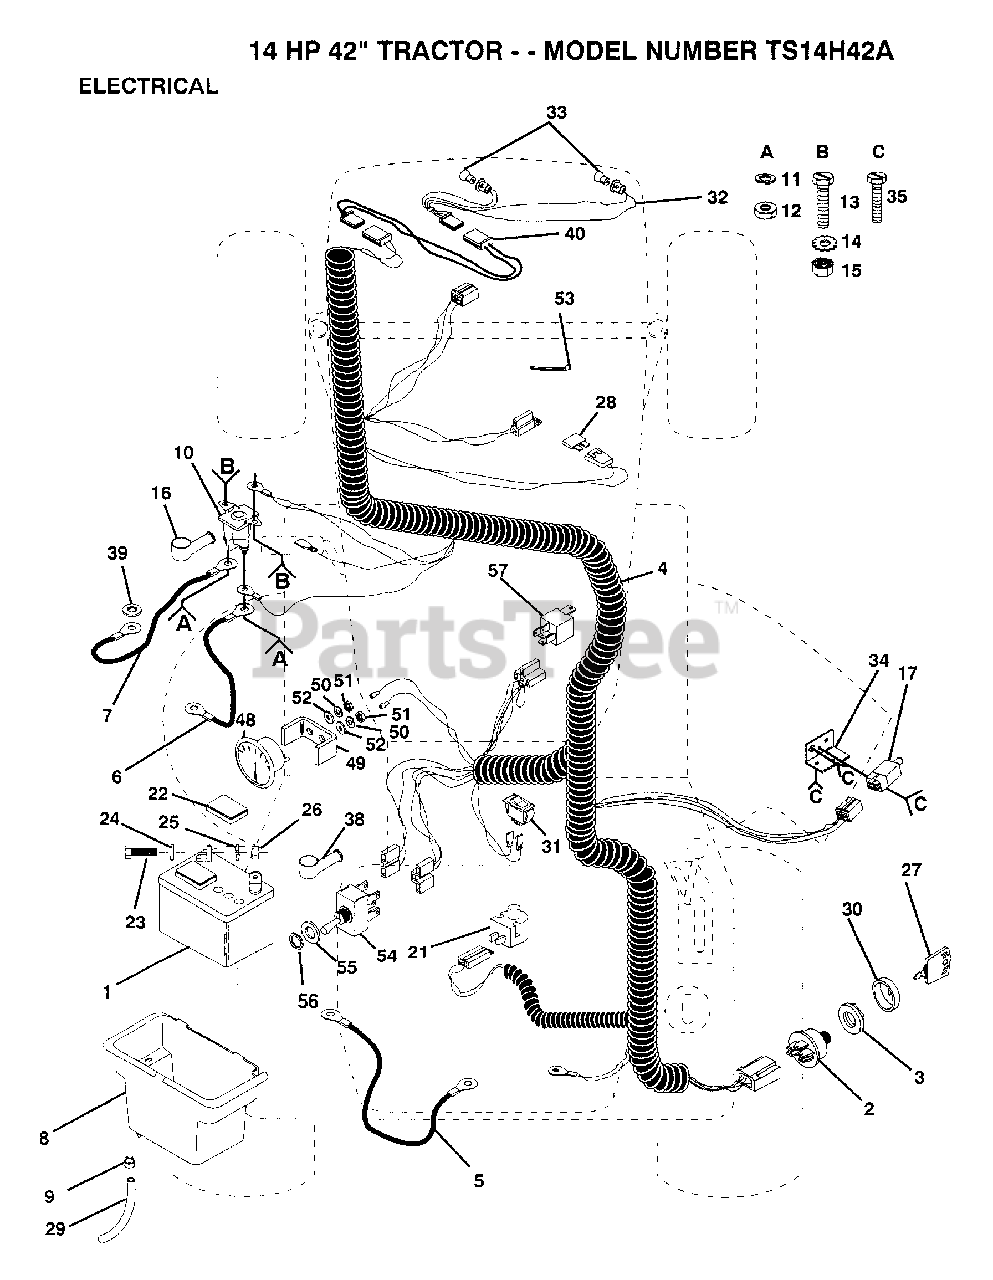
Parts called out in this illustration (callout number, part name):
3	NUT IGNITION
4	HARNESS.IGN
5	CABLE T
6	STARTER CABLE GT
7	CABLE-BATTERY T
8	BTRY CASE W/O LID
9	HOSE CLAMP T
12	NUT
13	BOLT
15	NUT
17	SWITCH INTERLOCKT
21	SWITCH SEAT
22	"CAP,BATTERY "
23	BOLT LT
24	WASHER
25	LOCKWASHER
27	KEY
28	FUSE HYT
29	TUBE T
31	SWITCH LT
32	"HARNESS,LIGHT SOC"
33	HEADLAMP BULB
34	BRACKET LT
35	SCREW
39	LOCKWASHER
40	HARNESS.PIGTAIL.H
48	AMMETER T
52	WASHER
53	WIRE TIE
55	WASHER
56	HEX NUT T
57	RELAY ASSY T
